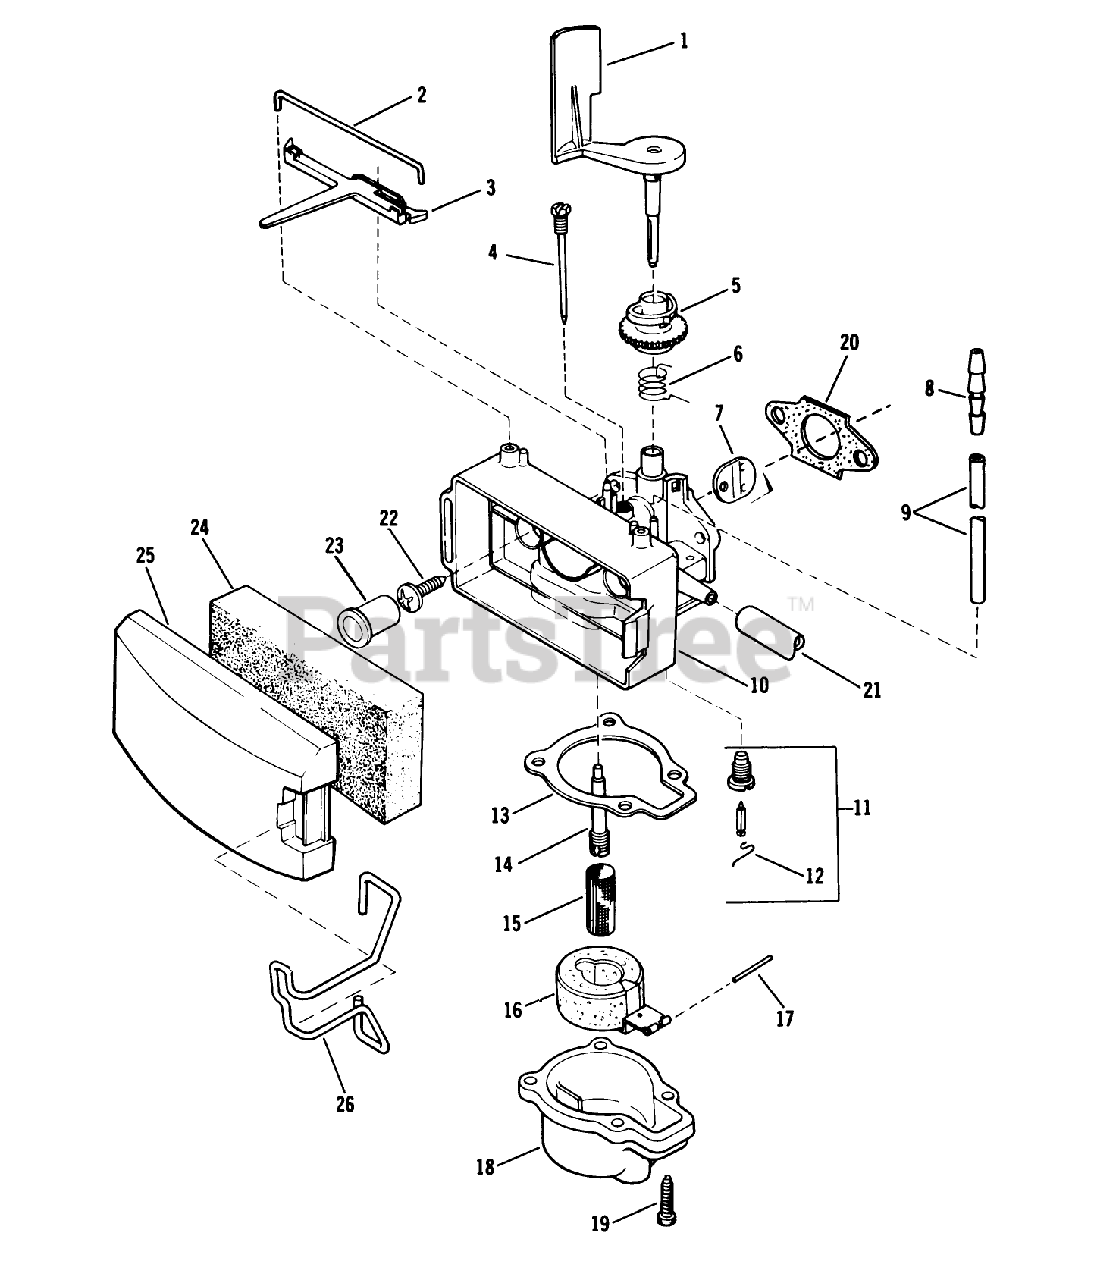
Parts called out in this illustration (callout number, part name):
2	RETAINER
3	LEVER S
4	NEEDLE ADJ. AY S
5	COLLAR-ADJUST, AIRVANE
6	SPRING,THROTTLE S
7	DISC S
8	REDUCER-CONNECTOR
9	TUBING S
10	CARB BODY S
15	FILTER-FUEL VS
19	SCREW-HH
20	GASKET CARB S
21	GAS LINE
22	SCREW
26	RETAINER-COVER, FILTER
